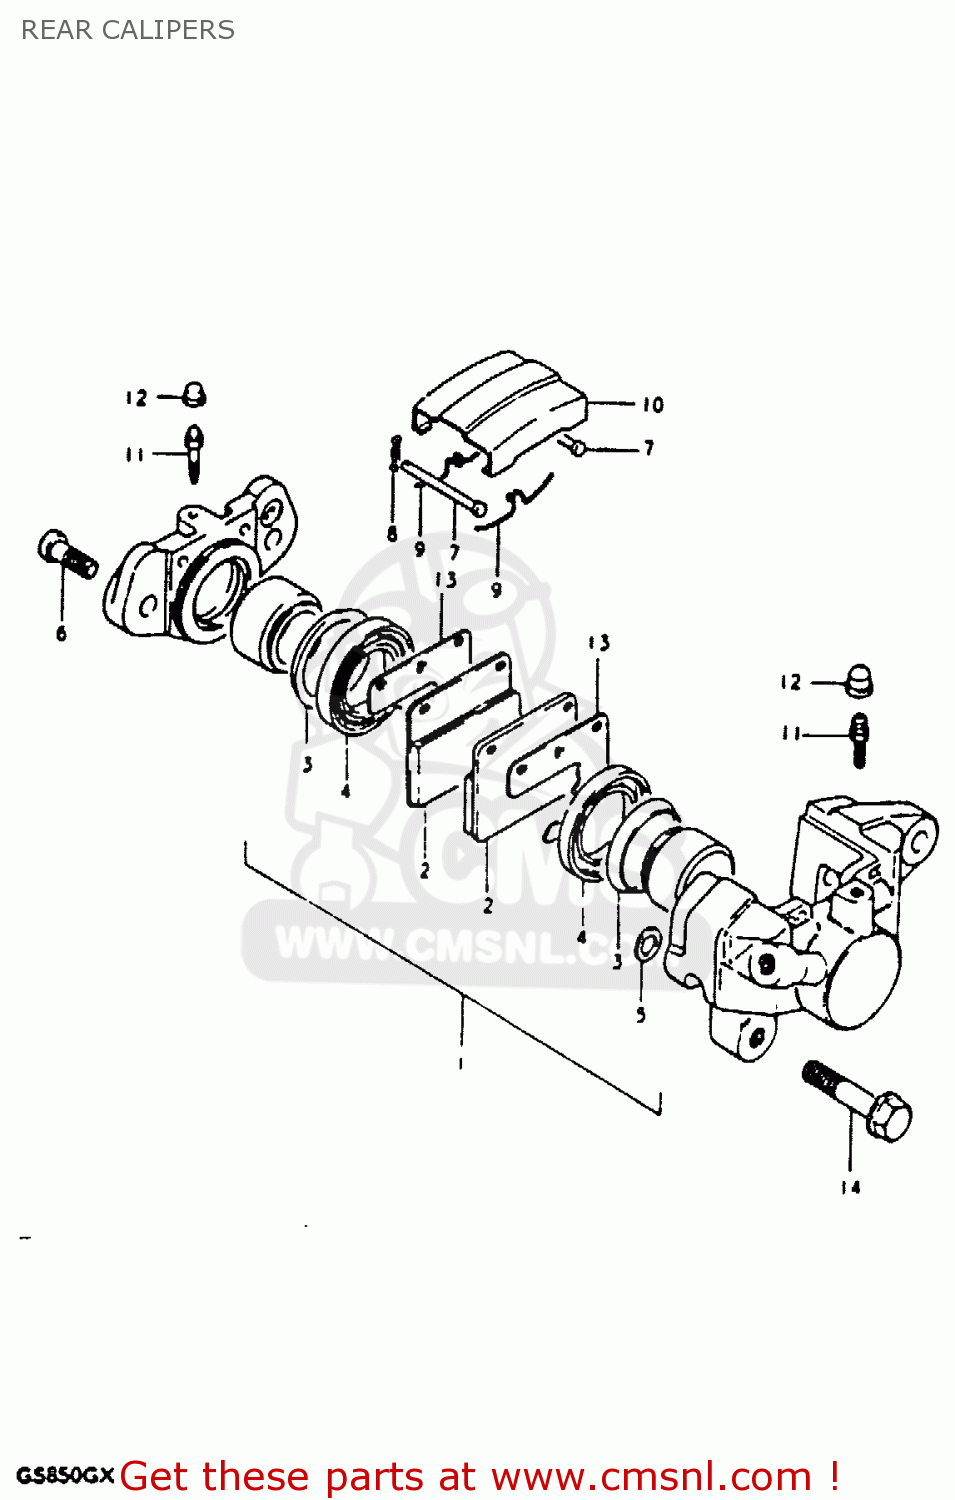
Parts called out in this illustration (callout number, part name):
1	PISTON SET
2	PAD,BRAKE
3	SEAL,PISTON
4	BOOT,PISTON
5	SEAL,PISTON
6	BOLT,HOUSING
7	PIN,PAD
8	CLIP,PAD PIN
9	SPRING
10	COVER,DUST
11	BLEEDER
12	CAP,BREATHER
13	SHIM,RR CALIPER
14	BOLT
